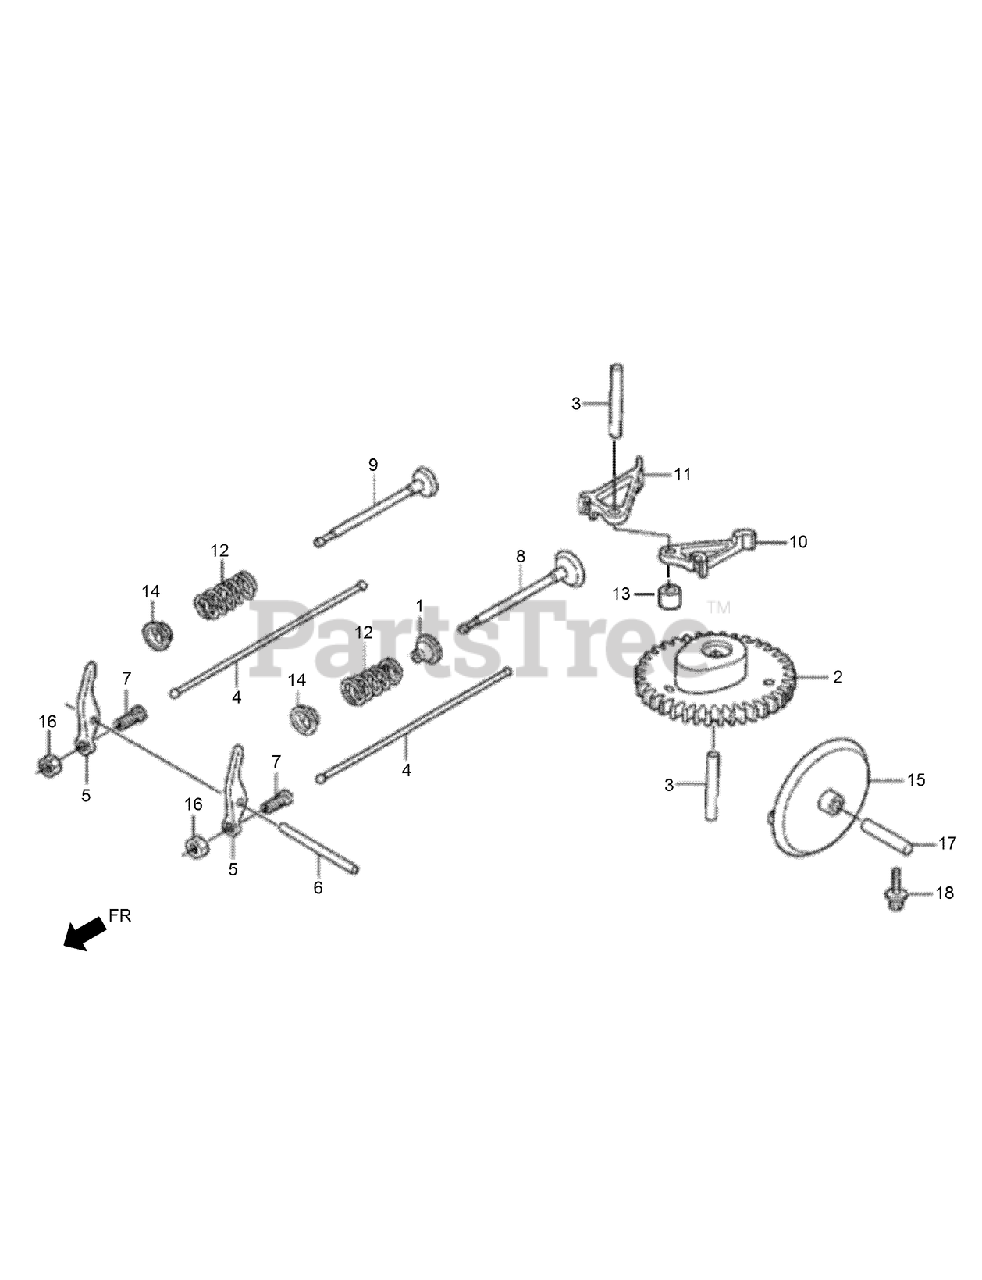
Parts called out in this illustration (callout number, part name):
1	SEAL-VALVE STEM
2	CAMSHAFT ASM
3	ROLLER
4	ROD-PUSH
5	ARM-VALVE ROCKER
6	ROLLER
7	PIVOT-ROCKER ARM
8	VALVE-INTAKE
9	VALVE-EXHAUST
10	LIFTER-VALVE
11	LIFTER-EXHAUST VALVE
12	SPRING-VALVE
13	COLLAR-LIFTER
14	RETAINER-VALVE SPRING
15	SLINGER-OIL
16	NUT-TAPPET ADJUSTING
17	ROLLER-6X25
18	BOLT-WASHER-5X16
